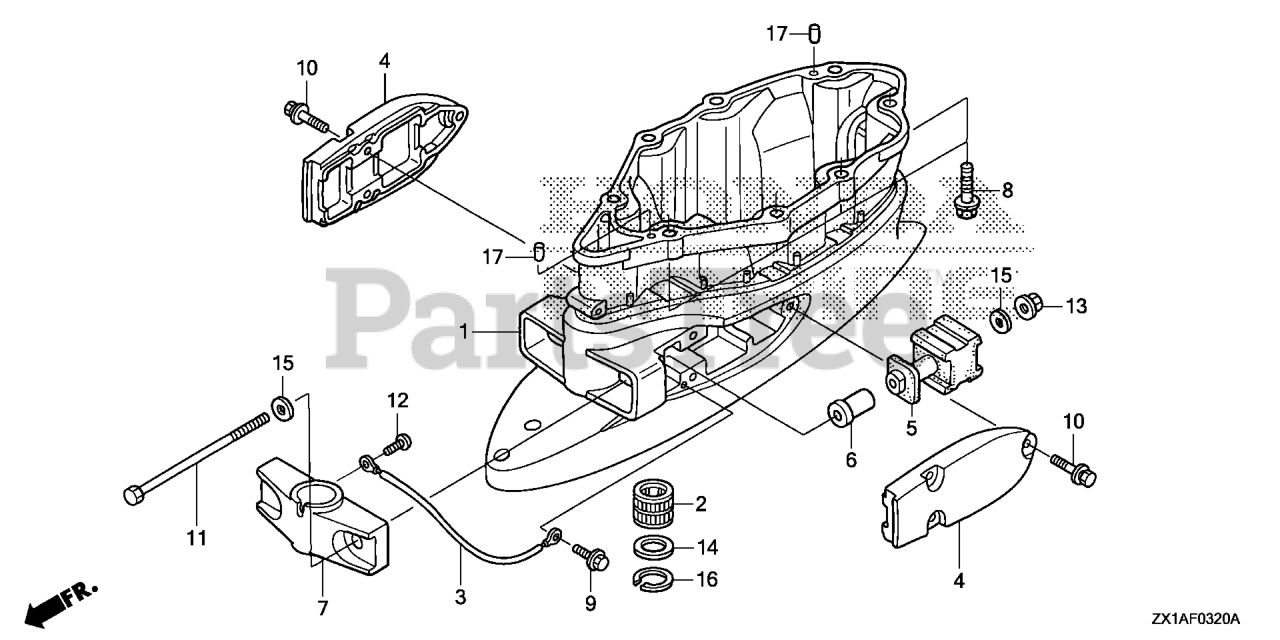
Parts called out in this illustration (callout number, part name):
1	CASE, EXTENSION *NHB14M* (AQUA MARINE SILVER METALLIC)
1	CASE,EXTENS*NH565*
2	BUSH, VERTICAL SHAFT
3	WIRE, LEAD (1.5X137MM)
4	HOUSING, MOUNTING (LOWER) *NHB14M* (AQUA MARINE SILVER METALLIC)
4	HSG,LWR MT*NH565*
5	RUBBER, MOUNT (LOWER)
6	COLLAR, MOUNTING (LOWER)
7	HOUSING, CENTER MOUNTING (LOWER) *NHB14M* (AQUA MARINE SILVER METALLIC)
7	HSG,LWR MT*NH565*
8	BOLT, FLANGE (10X40)
9	BOLT, FLANGE (6X12)
10	BOLT-WASHER (8X30)
11	BOLT, HEX. (12X225)
12	SCREW, PAN (6X8)
13	NUT, FLANGE (12MM)
14	WASHER (26MM)
15	WASHER, PLAIN (12MM)
16	CIRCLIP (INNER) (40MM)
17	PIN, DOWEL (6X10)
